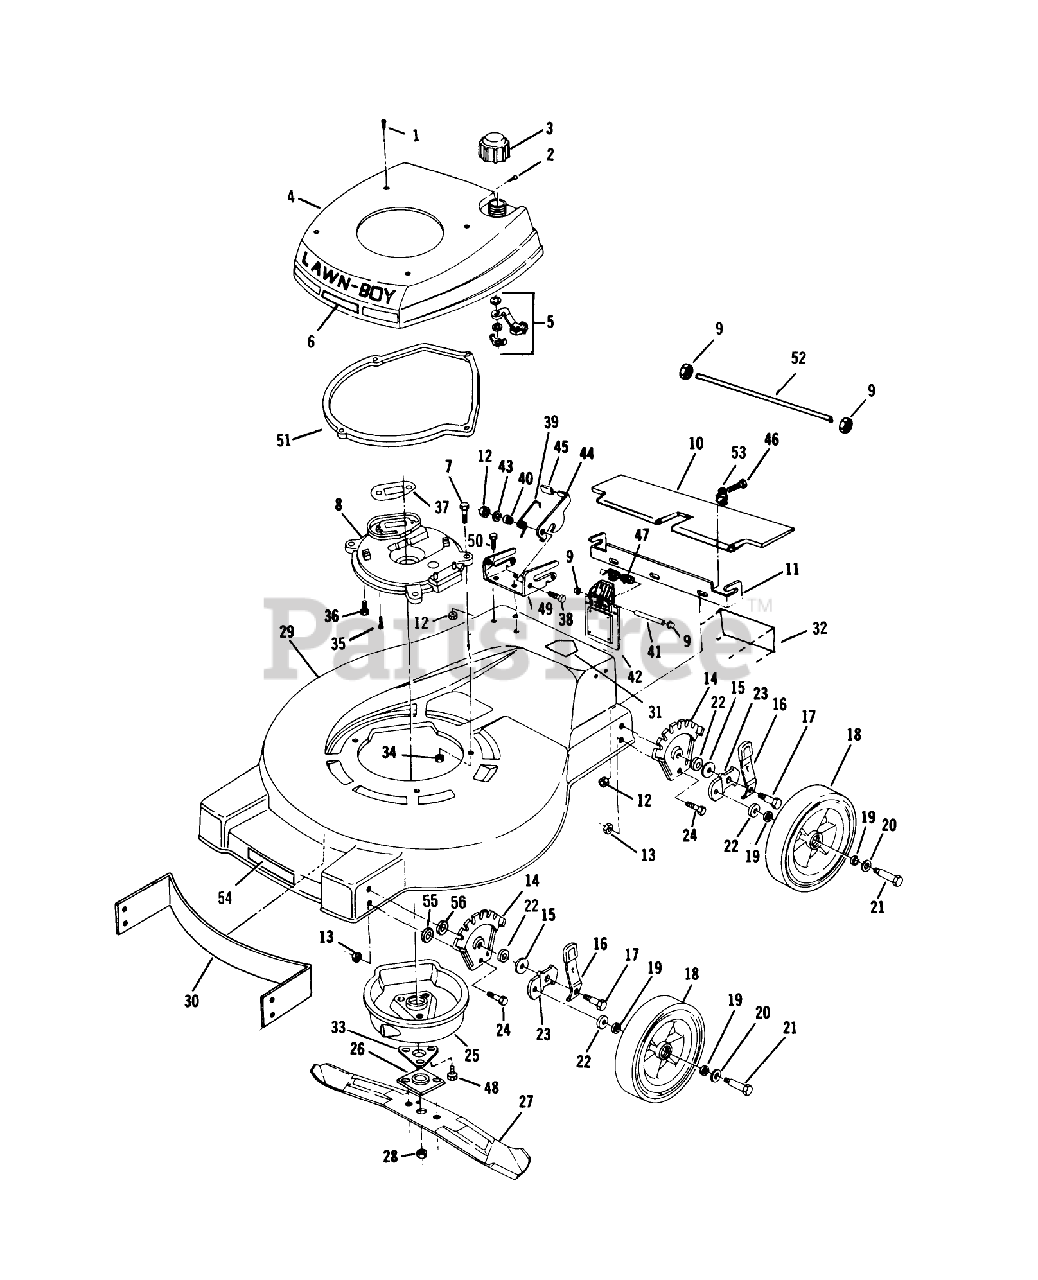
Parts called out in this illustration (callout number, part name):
1	SCREW LAWRENCE
2	SCREW S
3	FUEL CAP & INSERT
7	SCREW-HH
8	PLATE,MUFFLER F
10	T/SHIELD SM&P
12	LOCKNUT E
13	LOCKNUT
15	WASHER
16	KNOB&SPRING FORMCO
17	BOLT
19	WASHER
20	SPACER
21	BOLT WHEEL
22	WASHER WROUGHT
26	PLATE AND COLLAR ASM
28	NUT-BLADE
33	SUPPORT F
34	NUT-LOCK F
35	SCREW V
39	SPRING
41	ROD ROCK/HDWE
45	KNOB (S&R)
47	SPRING ASOC
48	SCREW
55	WASHER
56	WASHER
